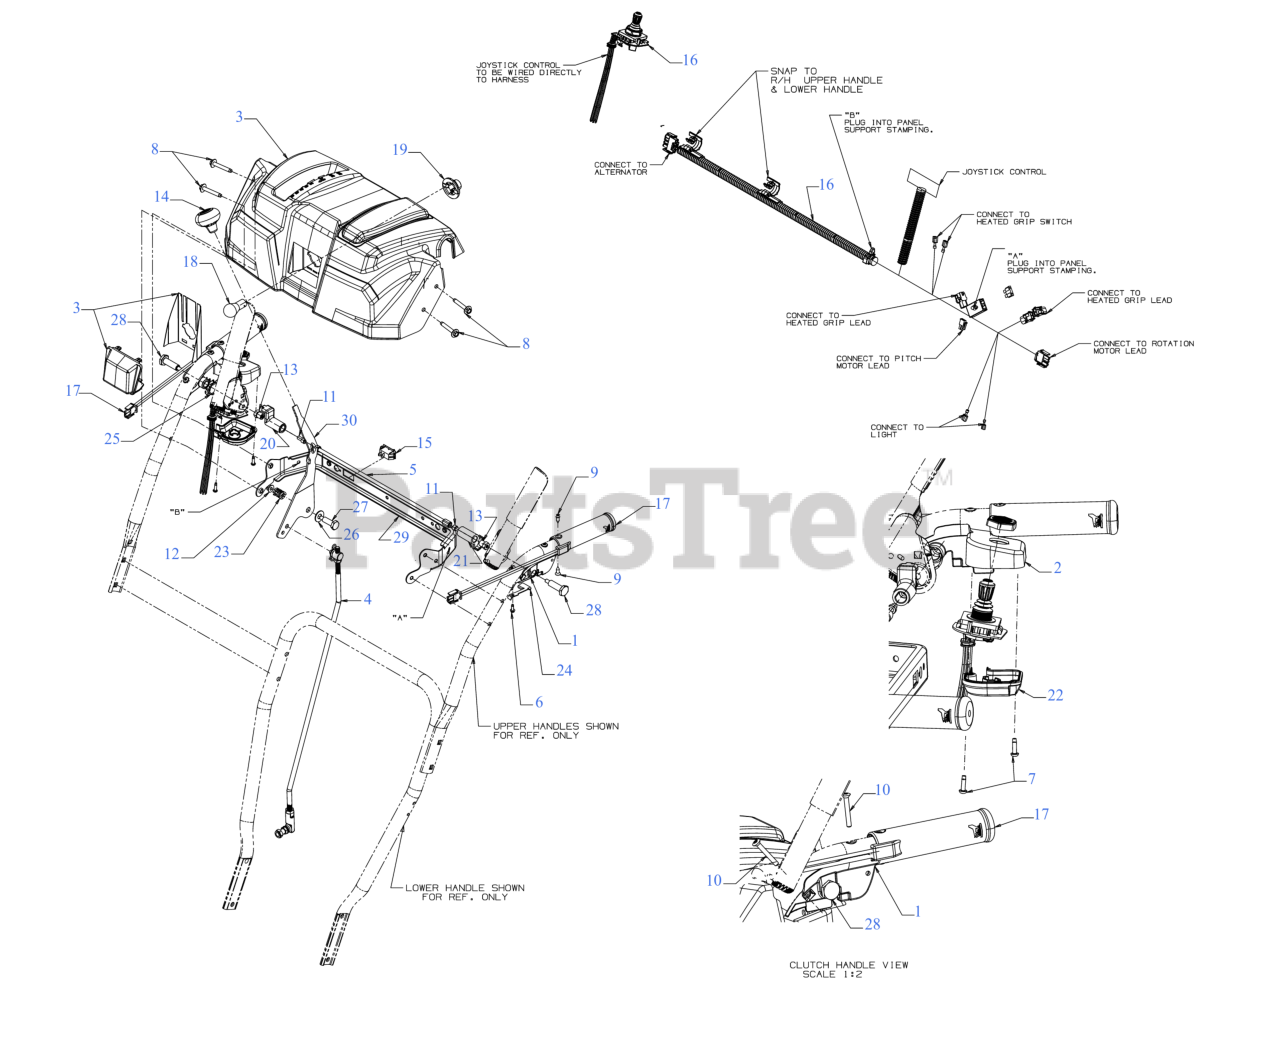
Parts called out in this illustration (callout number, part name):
1	CLUTCH LOCK HANDLE ASSEMBLY (LH)
2	CLUTCH HANDLE ASSEMBLY (RH)
3	HANDLE PANEL ASSEMBLY
4	SHIFT ROD ASSEMBLY
6	SCREW #8-16 x .50
7	SCREW .159 x .610
8	SCREW 1/4-20 x 1.625
9	SCREW-AB #12-24 x .625
10	SCREW #10-24 x 1.375
11	SCREW 1/4-20 x .50
12	FLANGE LOCK NUT
13	HEX NUT W/PATCH
14	SHIFT KNOB
15	HEATED GRIP SWITCH
16	4-WAY ELEC/HEAT GRIP HARNESS
17	HEATED GRIP
18	LAMP-12 VOLT
19	HEADLIGHT SOCKET (1/4 TURN)
21	CLUTCH LOCK CAM
22	JOYSTICK HOUSING COVER
23	COMPRESSION SPRING
24	CLUTCH SPRING
25	TORSION SPRING
26	FLAT WASHER .40X.88X.060
27	SHOULDER SCREW
28	SHOULDER SCREW .437 x 1.345 1/4-20
29	HANDLE SUPPORT BRACKET (POWDER BLACK)
